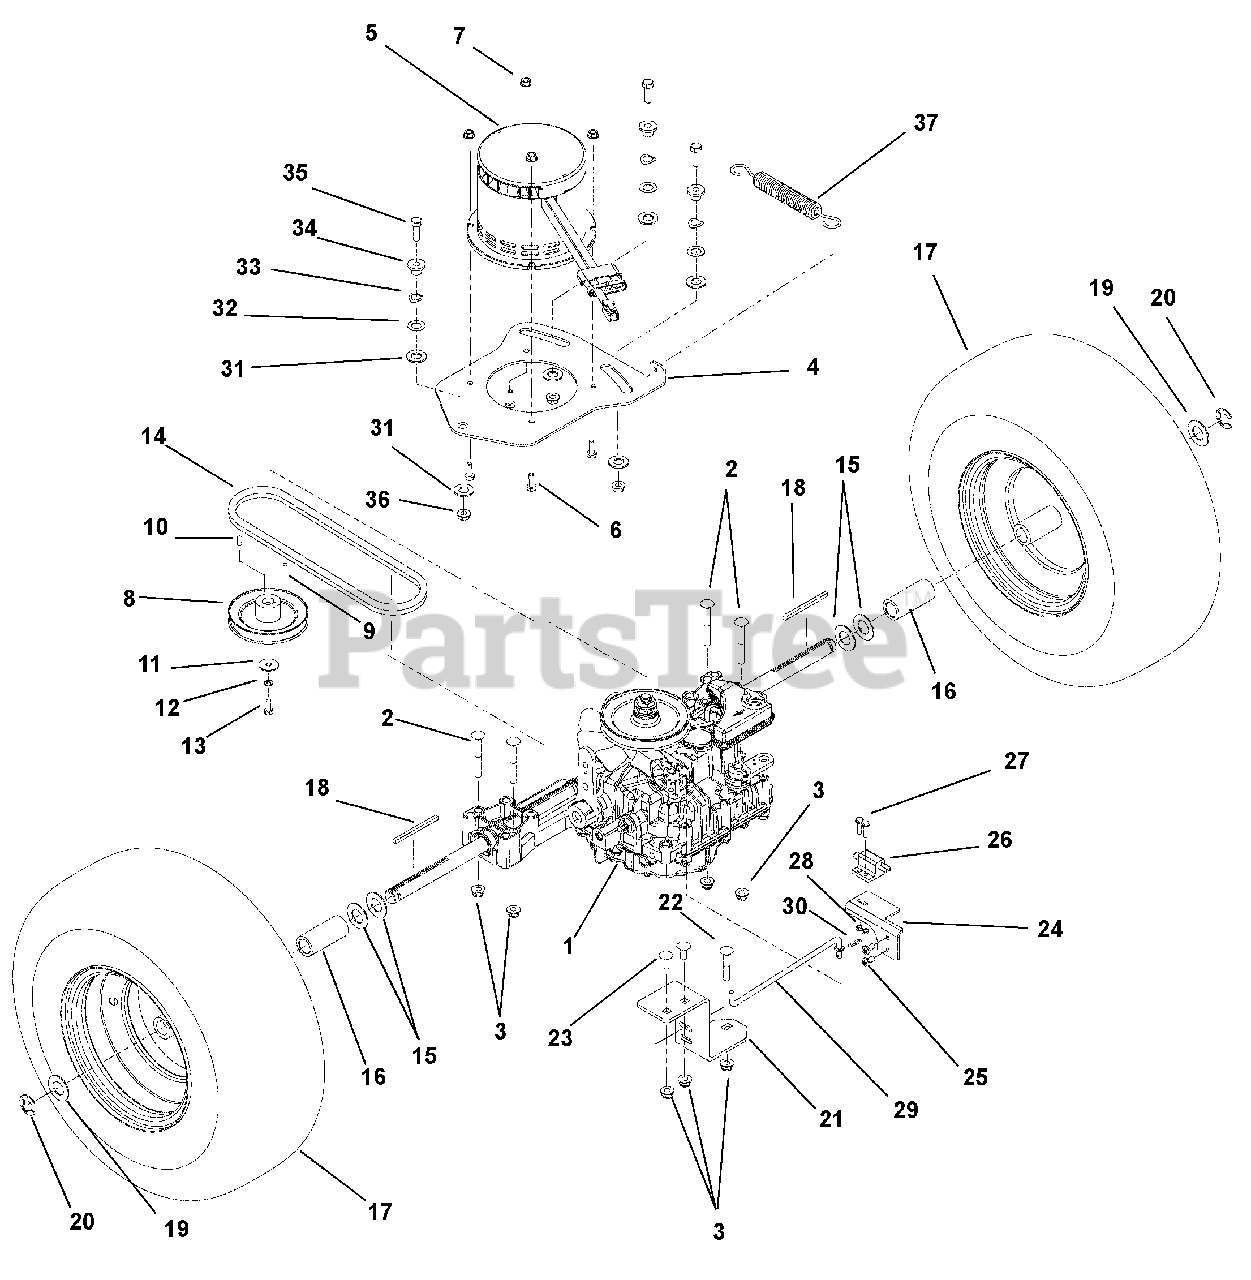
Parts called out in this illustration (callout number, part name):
1	TRANSMISSION,TUFF TORQ 21.53:1
2	@BLT-RDHDSQNK .31-18X2.50 G5YZ
3	@NUT-LK-NYL-FLG .31-18 YWZC
4	PLATE, MOTOR MOUNT
5	MOTOR, 4 HP ELECTRIC BRUSHLESS
6	@BLT-HEX .25-20X1.00 GR5 YWZC
7	@NUT-LK-NYL-FLG .25-20 YWZC
8	SHEAVE, PUMP .592 X 4.345
9	KEY-STR 5MMX25MMX5MM
10	SCR-SET .25-20X.38 SKHCUP OH
11	WSHR-FL-STL .281X1.000X.063
12	@WSHR-LK .25X.062 REG YWZC
13	@BLT-HEX M6-1X16 YWZC
14	V-BELT, SAE 380-RAW EDGE
15	WSHR-THRST .756 X 1.5 X .03
16	BSHG-SLV .750X1.250X2.56
17	TIRE/WHEEL ASSY 18X6.50 2 PLY
18	KEY-SQ .188X3.0X.188 SAE 8630
19	WSHR-HDND-THRST .755X1.40X.062
20	RG-RTNG-EXT .750X.050
21	STRAP, TORQUE
22	@BLT-RDHDSQNK .31-18X1.75 G5YZ
23	@BLT-RDHDSQNK .31-18X.75 G5YZ
24	BRACKET, N.M.I.R. MTG.
25	SCR-.25X.62 PN HD BOSSSCREW YZ
26	SWITCH- SINGLE POLE N.O.
27	@SCR-MCH 10-24X.75 HWH YWZC
28	@NUT-LK-NYL 10-24 W/INSRT YWZC
29	ROD, DUMP VALVE
30	PIN-HAIR INT .06X.18X.77
31	WSHR-FL-NYL .518X1.000X.080
32	WSHR-FL-STL .505X.875X.024 YWZ
33	WSHR-WAVE .50X.75X.015 .13FRHT
34	BSHG-FLG .325X.500X.513X.875
35	BLT-HEX .31-18X1.00 GR8 YWZC
36	@NUT-LK-TOP-FLG .31-18 YWZC
37	SPRING, EXTENSION
